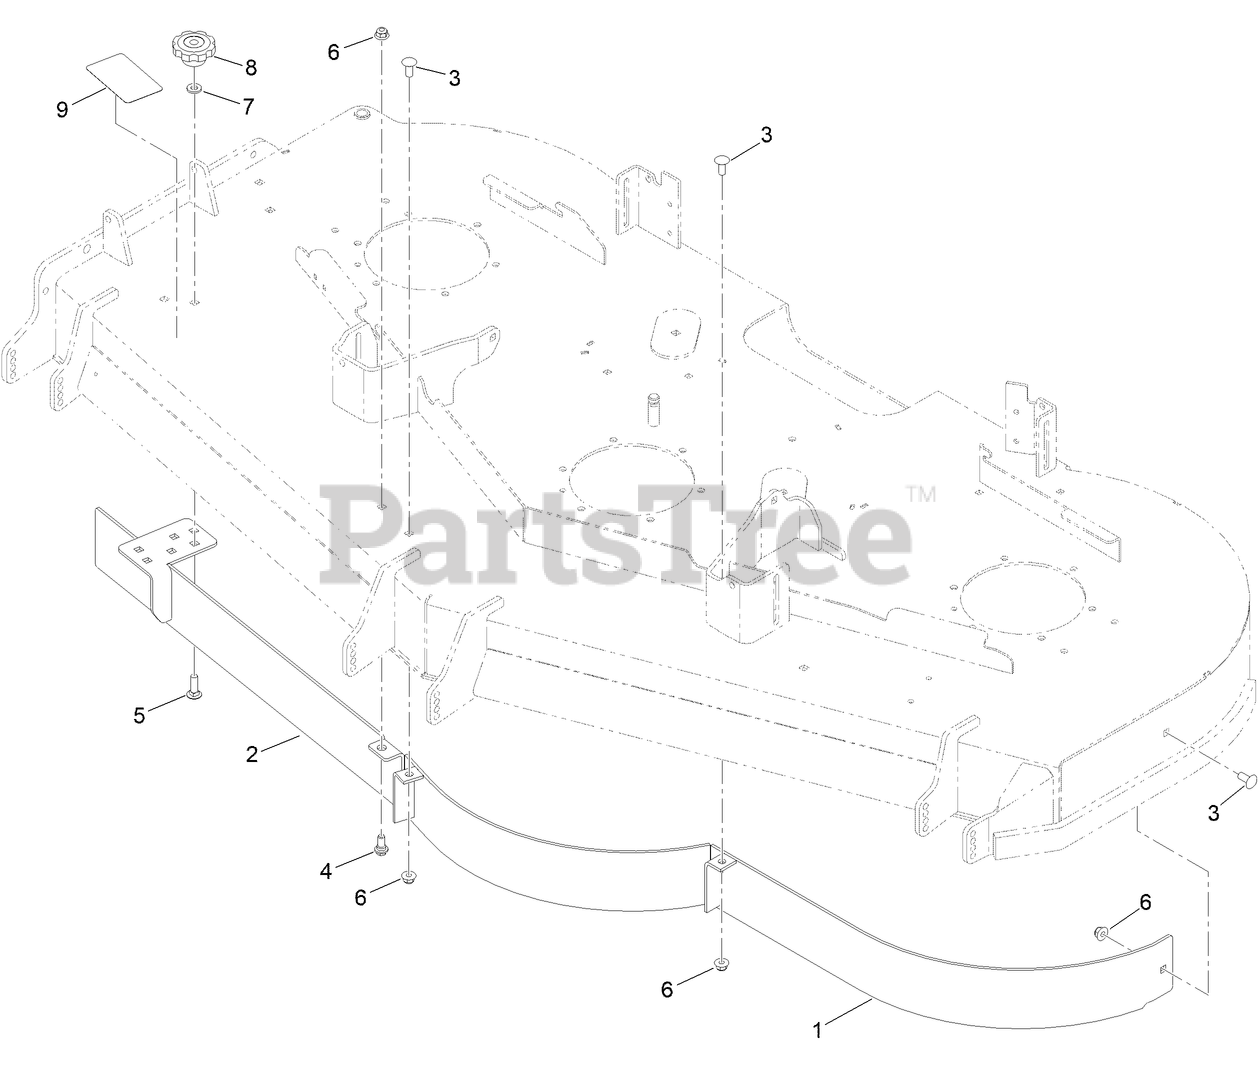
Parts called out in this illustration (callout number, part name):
2	BAFFLE-TURBO FORCE
3	SCREW-CARR
4	BOLT-SHOULDER
5	BOLT-CARR
6	NUT-HF, NI
7	WASHER-HARDENED
9	DECAL-ADJUSTABLE BAFFLE
